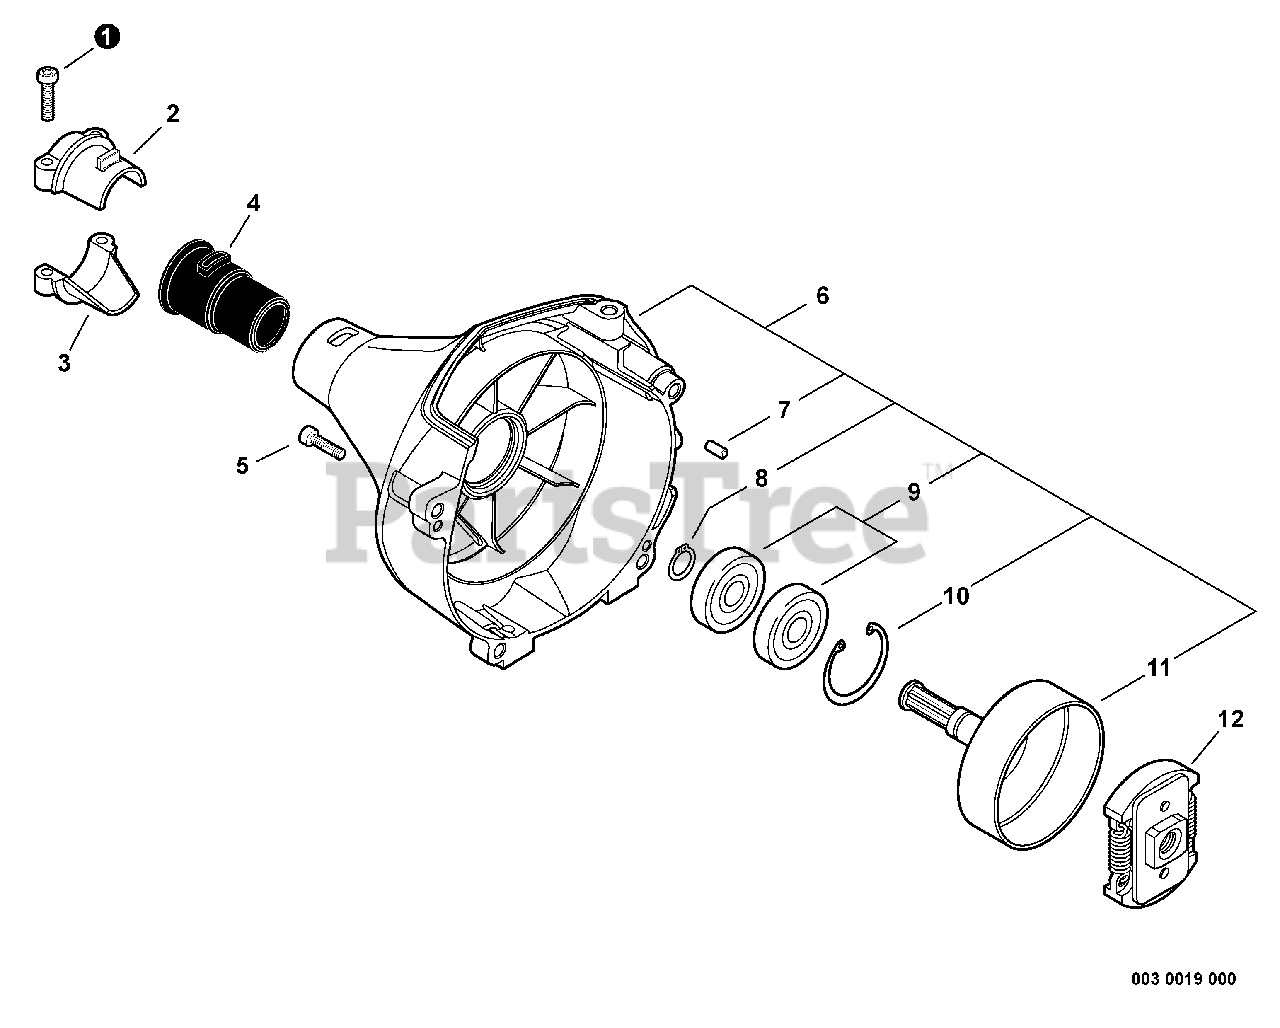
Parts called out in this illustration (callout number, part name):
1	SCREW - 5X20
2	CLAMP, MAIN PIPE - UPPER
3	CLAMP, MAIN PIPE - LOWER
5	SCREW - 4X16
6	FAN CASE ASSY
7	PIN - LOCATING
8	RING, RETAINING - 12
9	BEARING, BALL - 6001
10	RING, RETAINING - 28
11	DRUM, CLUTCH
12	CLUTCH ASSY
